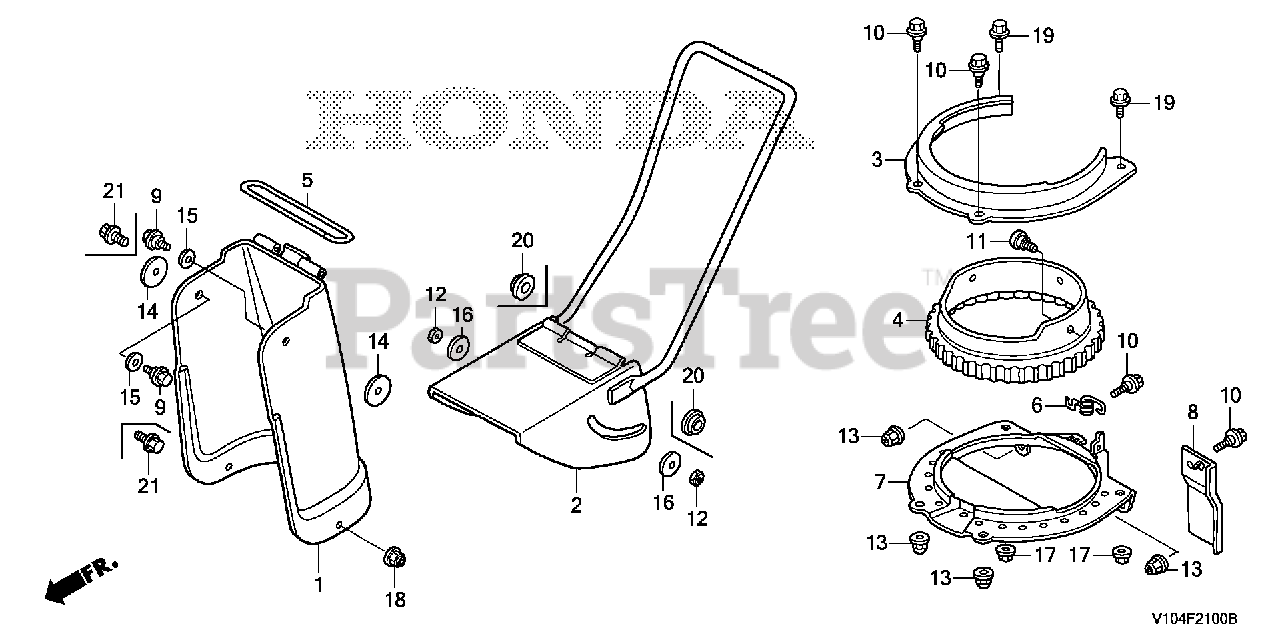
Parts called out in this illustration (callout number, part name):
2	GUIDE, CHUTE
3	PLATE, CHUTE SETTING
4	BUSH, CHUTE
5	PIN, CHUTE GUIDE
6	SPRING, CHUTE
7	RECEIVER, CHUTE
8	PLATE, HEAT GUARD
9	BOLT, CHUTE GUIDE
10	BOLT, CHUTE SETTING
11	BOLT, CHUTE SETTING
12	NUT, NYLON LOCK (6MM)
13	NUT, SELF-LOCK (6MM)
14	WASHER (10.2X32X1.6)
15	WASHER, WHEEL
16	WASHER, TANK CUSHION
17	NUT, FLANGE (6MM)
18	NUT, NYLON LOCK (6MM)
19	BOLT, FLANGE (6X12)
